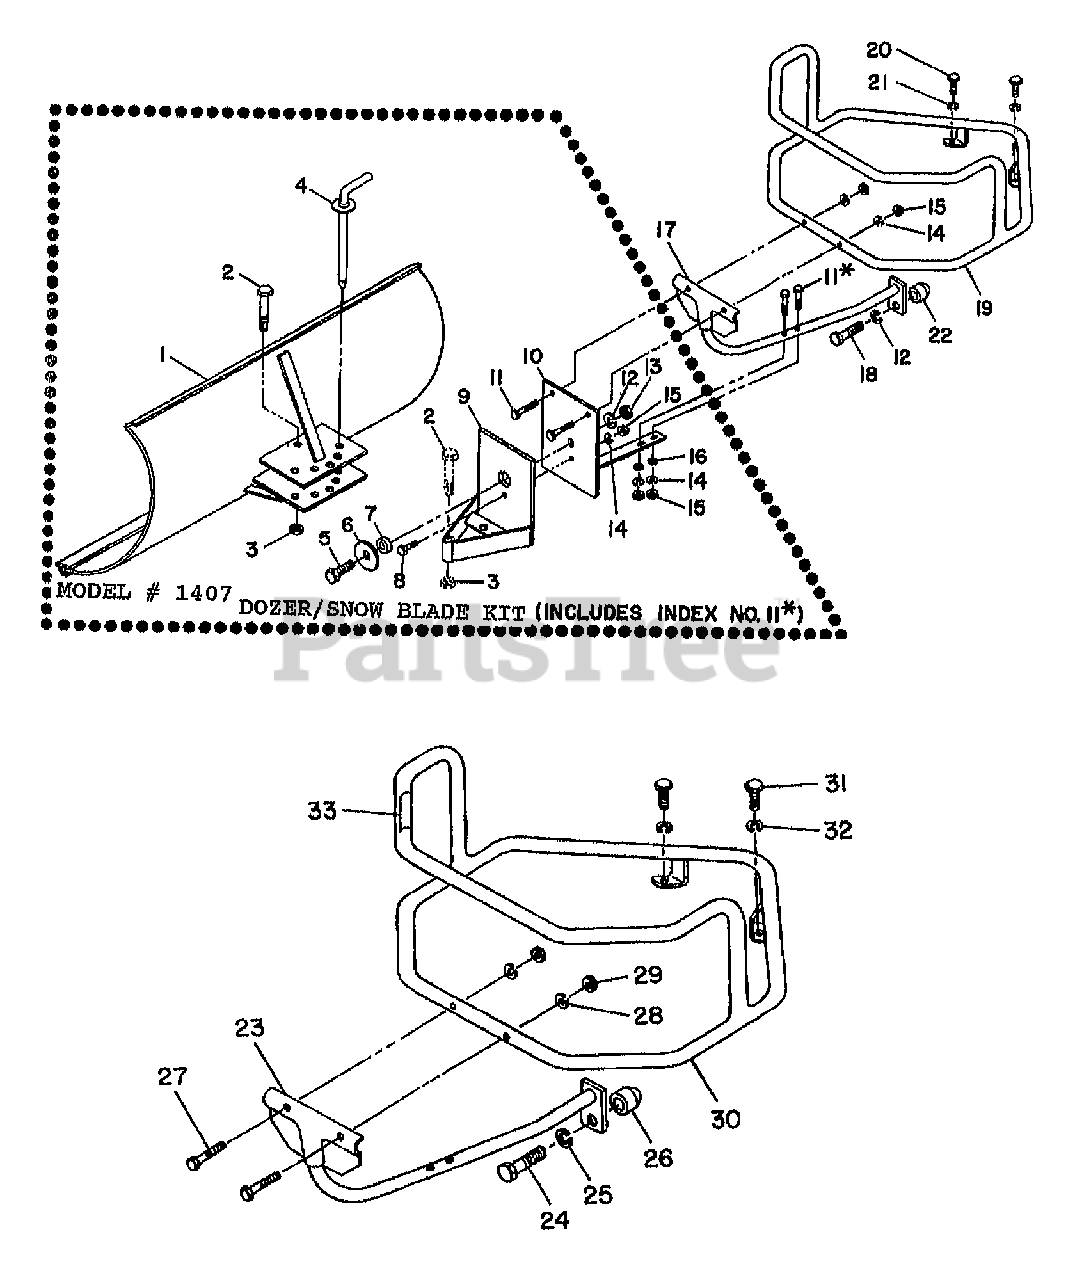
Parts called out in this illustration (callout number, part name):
1	BLADE-DOZER PAINTED
2	SCR-HH 1/2-13X3.0 G5
3	NUT-H/LK 1/2-13
4	INDEX PIN-DOZER PNT
5	SCR-HH 1/2-13X1.5 G5 ZP
6	WASHER-PLAIN 1/2 ZP
7	BUSHING-.75X.51X.41
8	SCR-HH 5/16-18X1.25 G5ZP
9	A FRAME-DOZER PNT
10	BRKT-MTG DOZER PNT
11	SCR-HH 5/16-18X1.75
12	WASHER-LK .5
13	NUT-HEX JAM 1/2-13
14	WASHER-LK .312 ZP
15	NUT-HEX 5/16-18 ZP
16	WASHER-FLAT 5/16 SAE
17	BRACE-BUMPER BOTTOM PNT
18	SCR-HH 1/2-13X2.0 G5 ZP
19	GUARD-BUMPER HORSE RED
20	SCR-HH 3/8-16X1.0 G5 ZP
21	WASHER-LK .375 @ DEPL
22	SPACER-1X.531X1.125 ZP
23	BRACE-BUMPER BOTTOM PNT
24	SCR-HH 1/2-13X2.0 G5 ZP
25	WASHER-LK .5
26	SPACER-1X.531X1.125 ZP
27	SCR-HH 5/16-18X1.5 G5 ZP
28	WASHER-LK .312 ZP
29	NUT-HEX 5/16-18 ZP
30	GUARD-BUMPER HORSE RED
31	SCR-HH 3/8-16X1.0 G5 ZP
32	WASHER-LK .375 @ DEPL
33	DECAL-BUMPER
